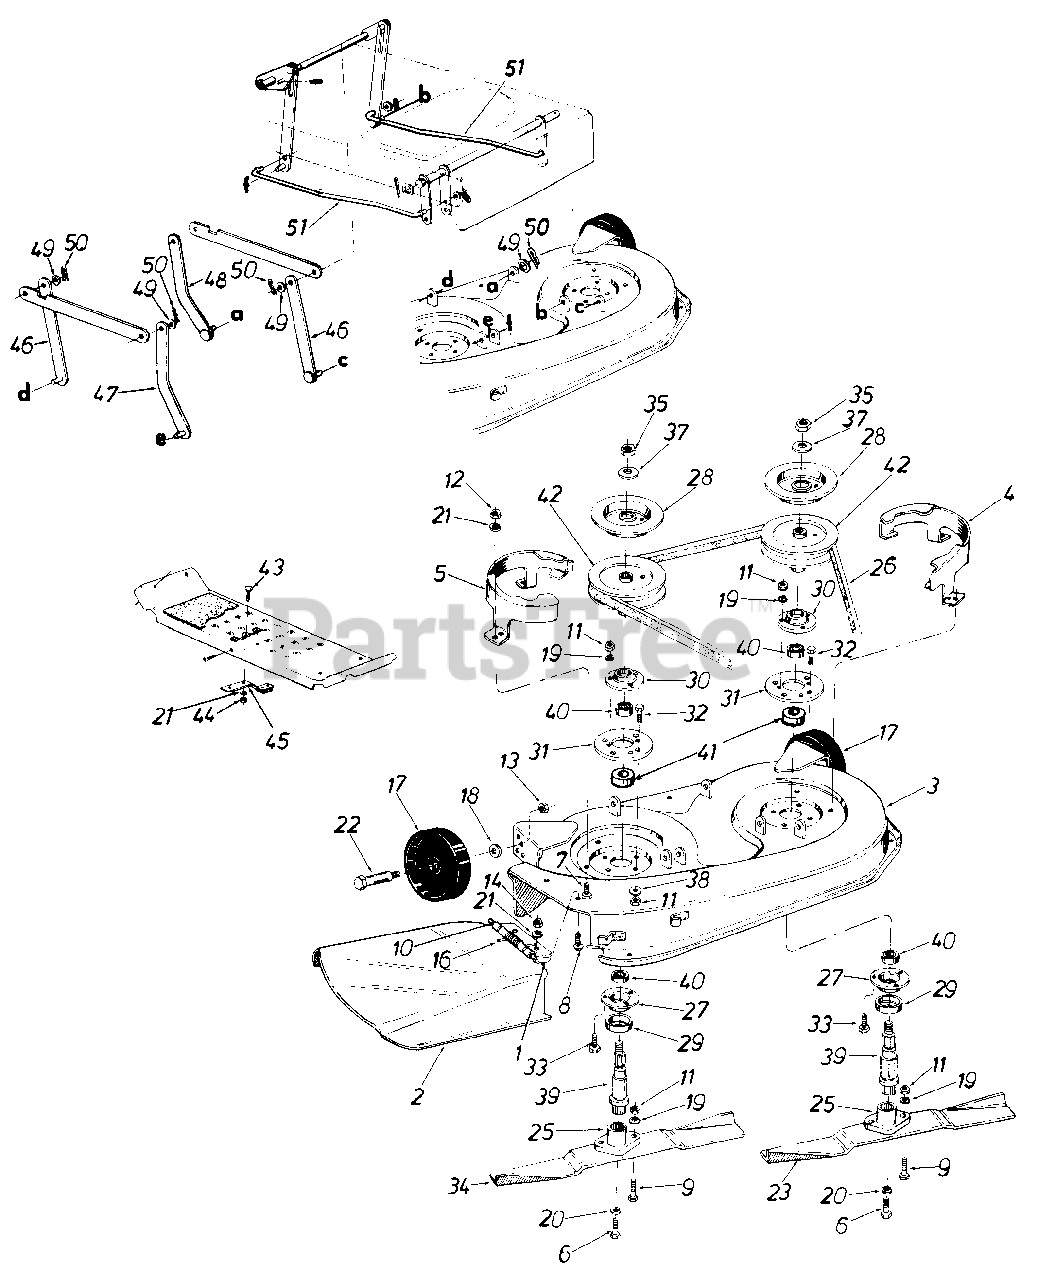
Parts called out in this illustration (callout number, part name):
1	Chute Bracket
2	Chute Deflector
3	38" Deep Deck Ass'y.
6	Hex Bolt 3/8-24 x 1.00"
7	Hex Bolt 1/4-28 x .62"
8	Truss Mach. Scr. 1/4-20 x .75"
9	Hex Scr Special 5/16-24 x 1.O"
10	Hinge Pin
11	1 Hex Nut 5/16-24 Thd.
12	Hex Nut 1/4-28 Thd.
13	Hex Top L-Nut 3/8-16 Thd.
14	Hex Jam Nut 1/4-20 Thd.
16	Torsion Spring
17	Deck Wheel 5"
18	Bell-Wash. .40" I.D. x .88" 0. D.
19	L-Wash. 5/16" I.D.
20	L-Wash. 3/8" I.D. H.D.
21	L-Wash. 1/4" I.D.
22	Shld. Bolt .498" Dia. x 1.53"
23	High-Lift Blade L.H.
25	Blade Adapter
26	5L V-Belt
27	Bearing Housing 1.85" I.D.
28	Brake Disc
29	Bearing Shield
30	Open Brg. Housinq 1.85" I.D.
31	Spindle Mounting Plate
32	Hex Bolt 5/16-24 x .75"
33	Hex Bolt Special 5/16-24 x 1.O"
34	High-Lift Blade R.H.
35	Hex Jam Nut 5/8-18 Thd.
37	L-Wash. 518" I.D.
38	Bell-Wash. .345" I.D. x .88" O.D.
39	Blade Spindle
40	Ball Brg. .787" I.D. x 1.85" 0. D.
41	Spacer 1.0" O.D. x .790" I.D. x .350"
42	5" Dia. Pulley
43	Carr. Bolt 1/4-20 x .62"
44	Hex Nut 1/4-20 Thd.
45	Blade 8rake Ass'y.
46	Link Deck Hanger Ass'y.
47	Link Deck Hanger Ass'y.
50	Inter. Cotter Pin .50" Dia.
51	Stabilizer Rod
